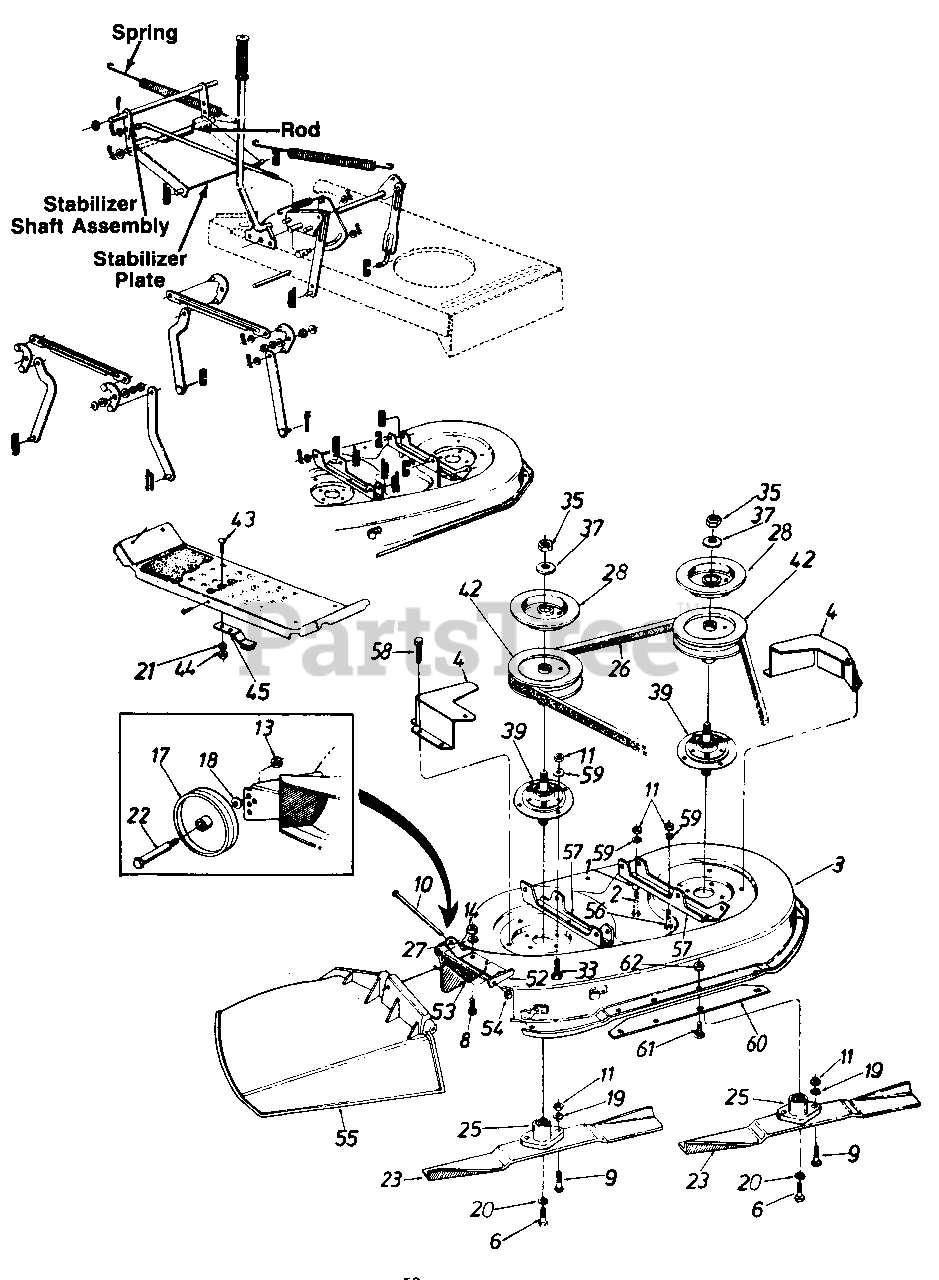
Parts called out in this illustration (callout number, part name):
1	Spacer .33" I.D. x .88"
2	Hex Bolt 5/16-24 x 1.25" Lg.
3	38" Deck Ass'y. w/Deck Wheels
6	Hex Bolt 3/8-24 x 1.0" Lg.
8	Hex Bolt 1/4-20 x .62"
9	Hex Bolt Special 5/16-24 x 1.0n
10	Hinge Pin
11	Hex Nut 5/16-24 Thd.
13	Hex Top L-Nut 3/8-16 Thd.
14	Hex Nut 1/4-20 Thd.
17	Deck Wheel-5n
18	Bell-Wash. .40" I.D. x .88n O.D.
19	L-Wash. 5/16" I.D.
20	L-Wash. 3/8" I.D.-H.D.
21	L-Wash. 1/4" I.D.
22	Shld. Bolt .498" Dia. x 1.53"
23	High-Lift Blade
25	Blade Adapter
26	V-Belt
27	Bell-Wash. 1/4" I.D.
28	Brake Disc
33	Hex Bolt 5/16-24 x .75" Lg.
35	Hex Jam Nut 5/8-18 Thd.
37	L-Wash. 5/8" I.D.
39	Blade Spindle Ass'y. Comp.
42	5" Dia. Pulley
43	Carr. Bolt 1/4-20 x .62
44	Hex Nut 1/4-20 Thd.
45	Blade Brake Ass'y.
52	Hinge Mtg. Brkt.
53	Torsion Spring
55	Chute Ass'y. Comp.
56	Hex Bolt 5/16-24 x .75n Lg.
59	Bell-Wash. .345" l.D. x .88"
62	Hex Sems Nut 1/4-20 Thd.
